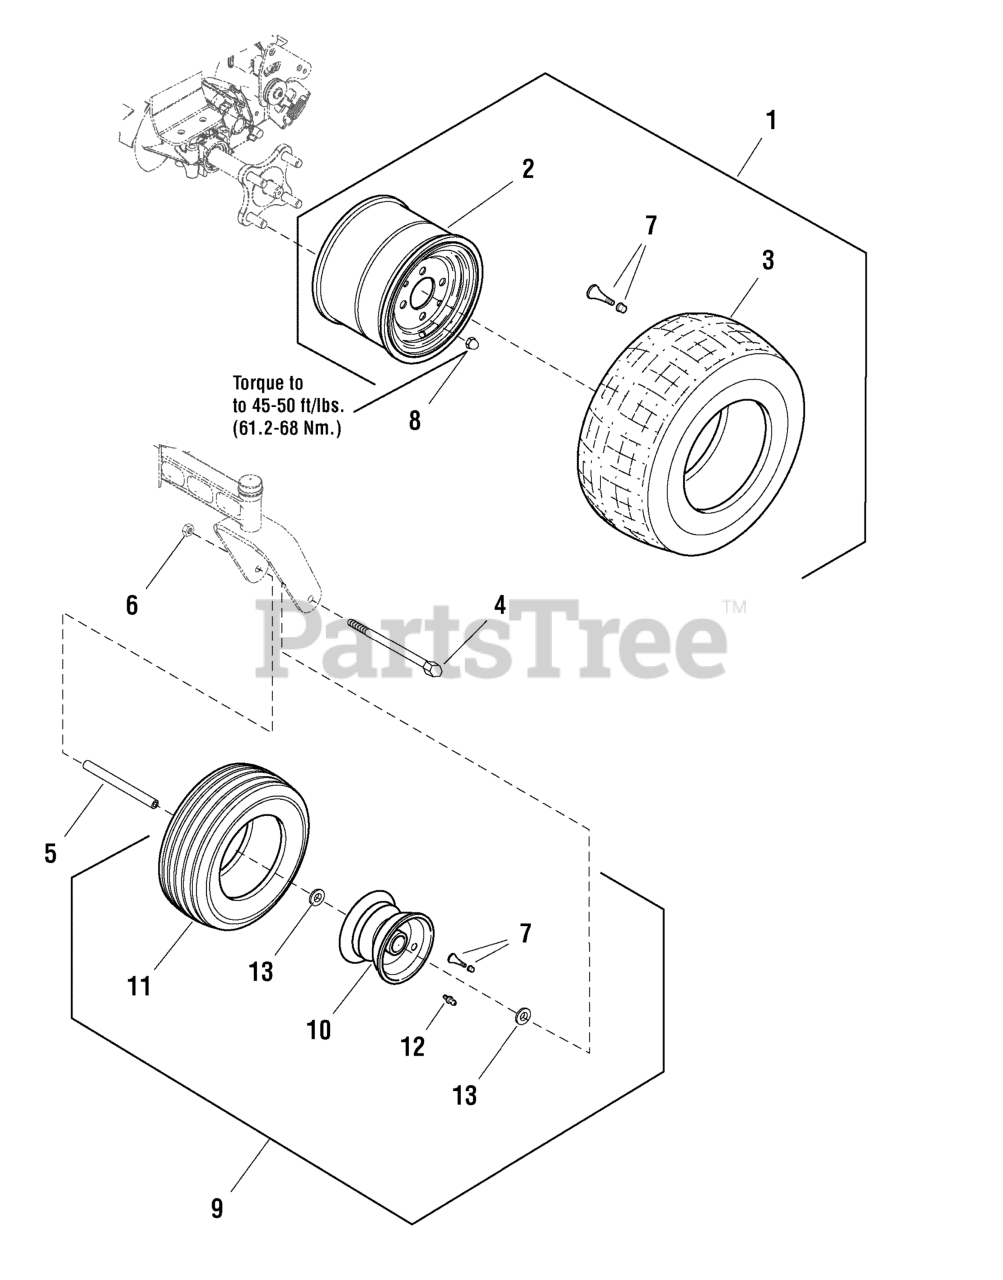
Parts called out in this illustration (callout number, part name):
1	WHEEL & TIRE ASSEMBLY, 18 x 8-1/2-8
2	WHEEL, 18 x 8-1/2 - 8
3	TIRE, 18 x 8-1/2 - 8
4	CAPSCREW, Hex Head
5	TUBE, Caster Wheel
6	NUT, Hex Center Lock
7	VALVE STEM & CAP
8	NUT, Hex Lug, 7/16-20
9	WHEEL & TIRE ASSEMBLY, 11 x 4-5
10	WHEEL, 11 x 4 - 5
11	TIRE, 11 x 4 - 5
12	FITTING, Lube
13	BUSHING, Wheel
